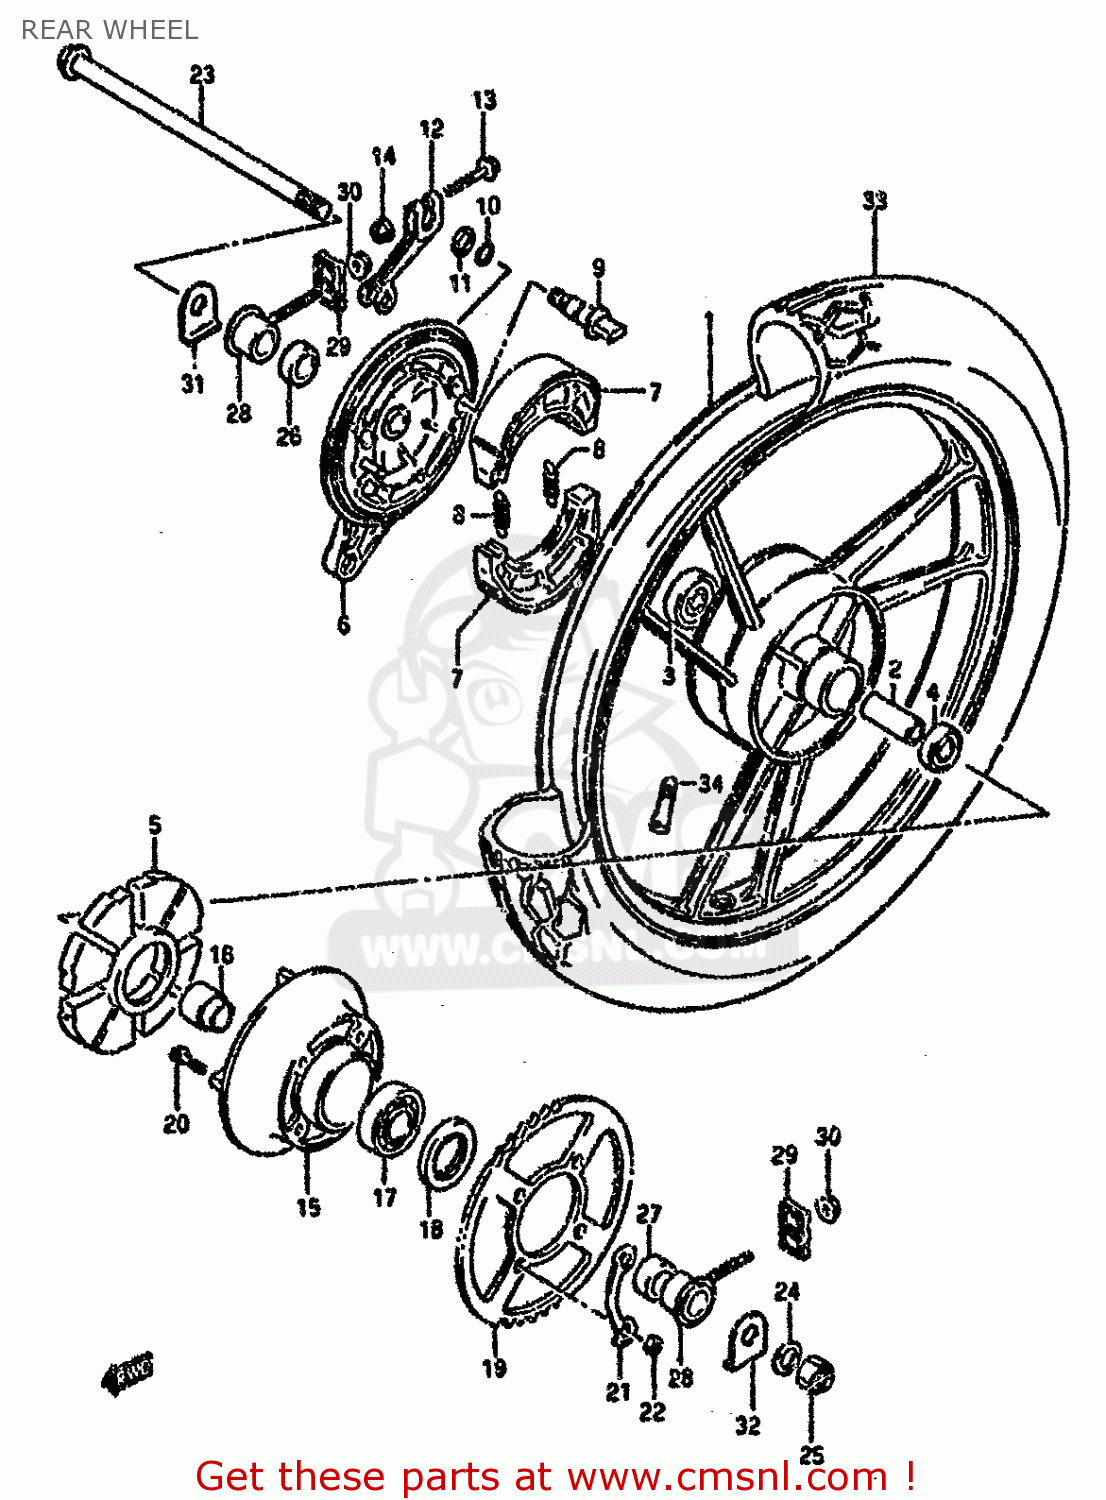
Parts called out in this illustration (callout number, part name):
1	WHEEL, REAR, MT1.85*18 (BLACK)
2	SPACER(15.3X21.7X63)
3	BEARING
4	BEARING
5	ABSORBER,RR HUB SHOCK
6	PANEL,REAR BRAKE ANCHOR
7	SHOE,BRAKE
8	SPRING(L:34)
9	CAM,FRONT BRAKE
10	O-RING (D:2.4 ID:13.8)
11	WASHER (14.5X22X1.6)
12	CAM,LEVER
13	BOLT 6X35
14	NUT
15	DRUM,RR SPROCKET
16	RETAINER,RR SPROCKET MTG
17	BEARING(20X47X14)
18	SEAL,OIL(28X47X7)
19	SPROCKET,REAR (NT:48)
20	BOLT
21	WASHER
22	NUT
23	AXLE, REAR
24	WASHER
25	NUT
26	SPACER,RR AXLE,R
27	SPACER,RR AXLE,L
28	ADJUSTER,CHAIN
29	PLATE,CHAIN ADJUSTER GUIDE
30	NUT
31	WASHER,CHAIN ADJUSTER,R
32	WASHER,CHAIN ADJUSTER,R
33	TIRE, T/L REAR (90/90-18 51P)
34	VALVE,TIRE
